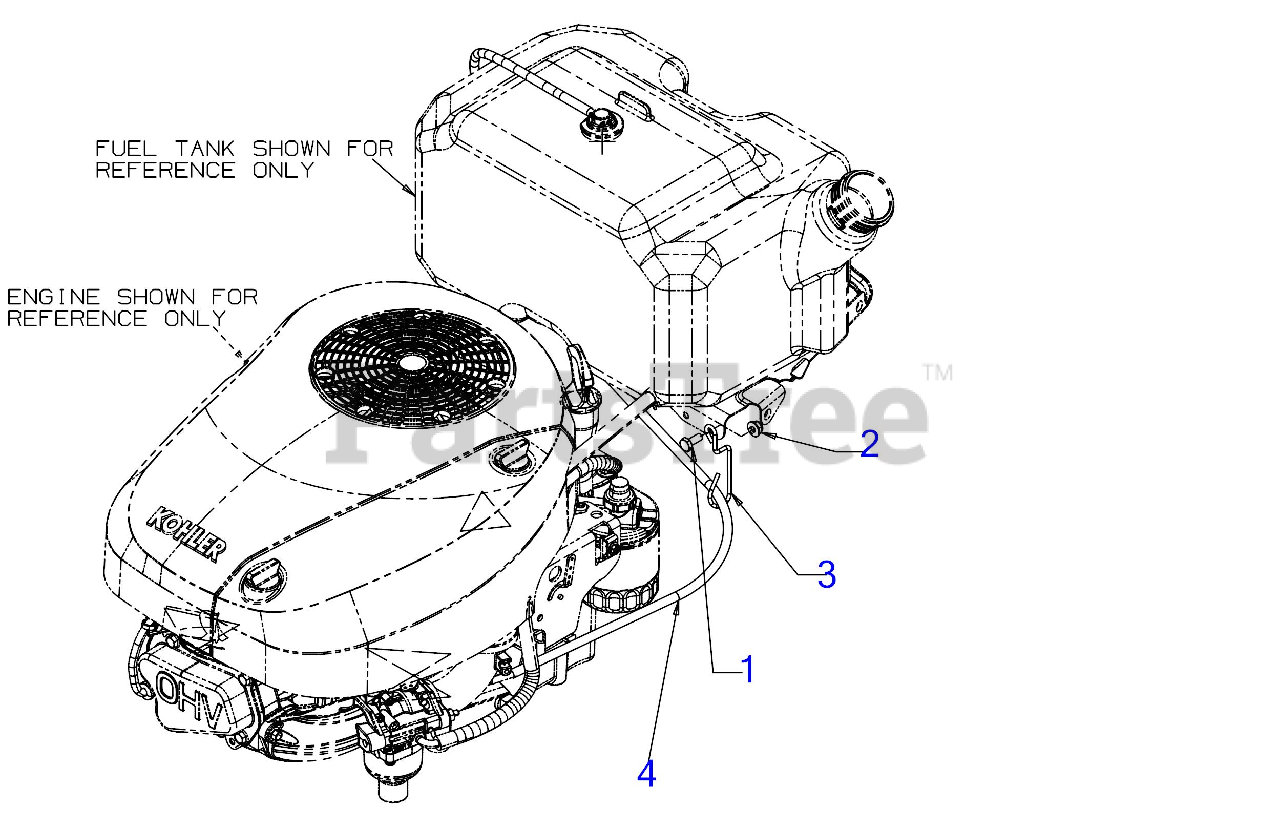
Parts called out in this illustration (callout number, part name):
1	SCREW 1/4-20 x .620 GR5
2	FLANGE LOCK NUT
3	CABLE GUIDE WIRE
4	VENT HOSE 3/16 ID
